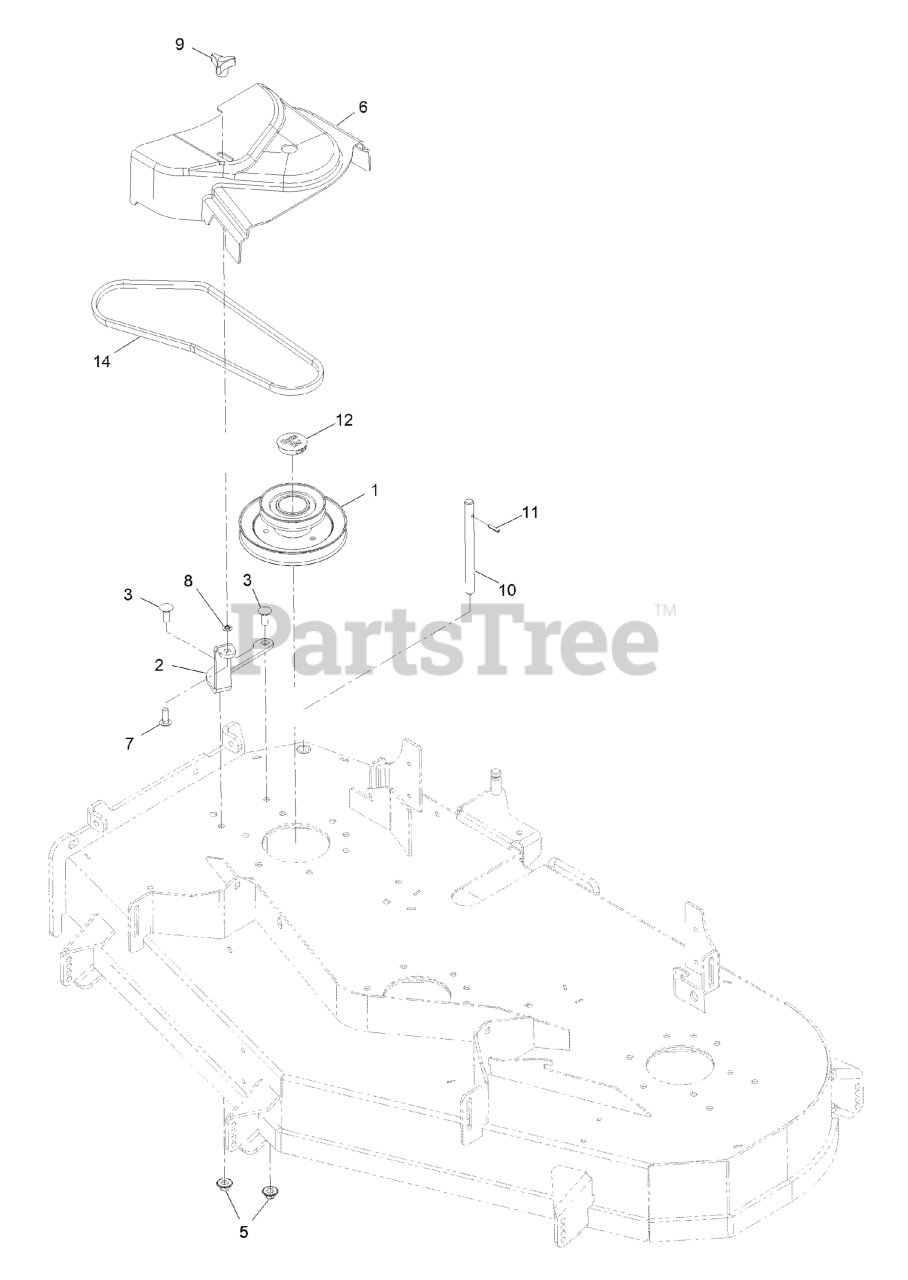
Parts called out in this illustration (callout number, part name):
1	JACKSHAFT,UV DRIVE 524 SP
2	BRACKET, SMALL UV BELT CO
3	BOLT-CARR
5	Nut-Nyloc 3/8-16 Flg
6	COVER-BELT, UV 52
7	BOLT-CARR
8	RING-RETAINING, BOLT
9	KNOB-3 PRONG
10	SHAFT-CATCHER, GRASS
11	PIN-ROLL
12	PLUG, BLACK NYLON 1.75
14	BELT, BLOWER 52"DECK
